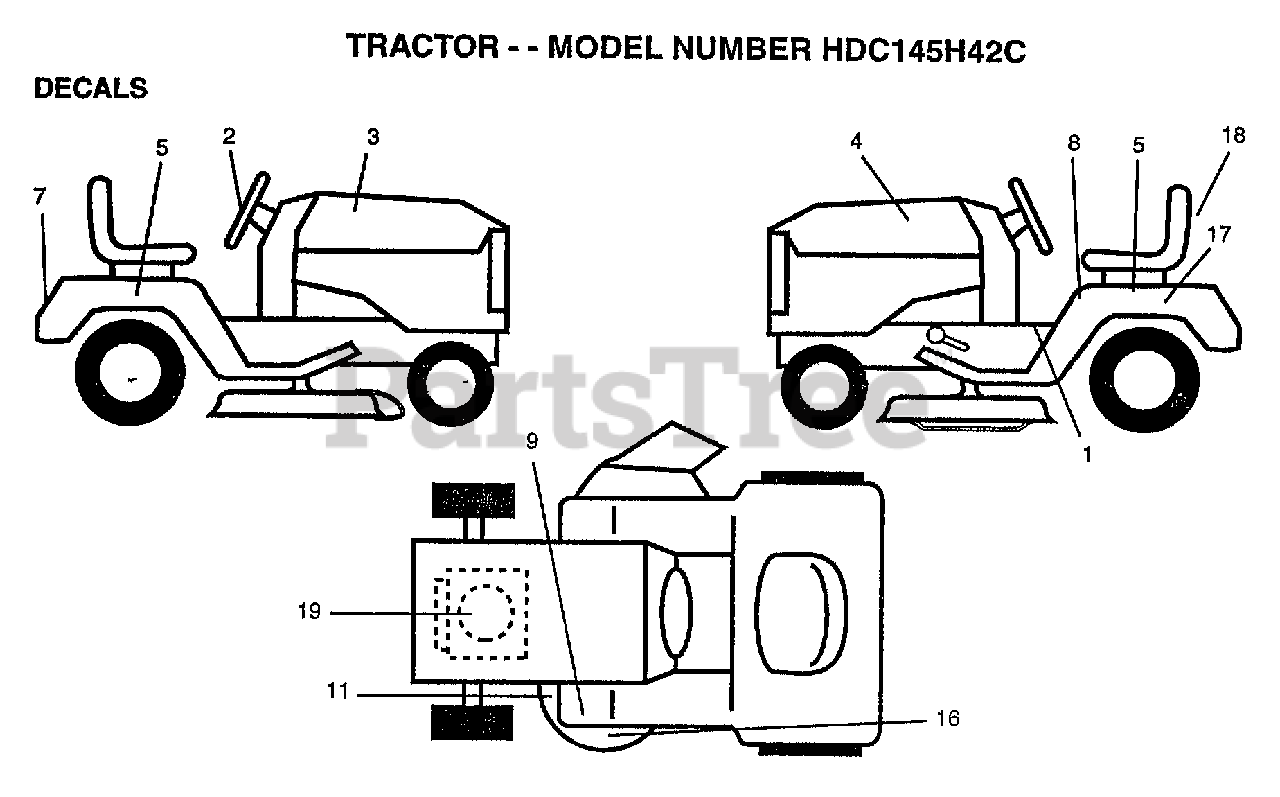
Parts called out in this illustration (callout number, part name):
1	"DECAL-SADDLE,INST"
2	"DECAL WHEEL,STEER"
3	"DECAL-HOOD,RH"
4	"DECAL-HOOD,LH"
5	"DECAL FENDER,SD"
7	"DECAL FENDER,LOGO"
8	"DECAL FENDER,DANG"
9	DECAL CLUT/BRAKE
11	DECAL
16	"DECAL DECK,MULCH"
17	DECAL.BATRY.3-3908
18	"DECAL SEAT,ACC"
19	"DECAL REPLCMT,ENG"
